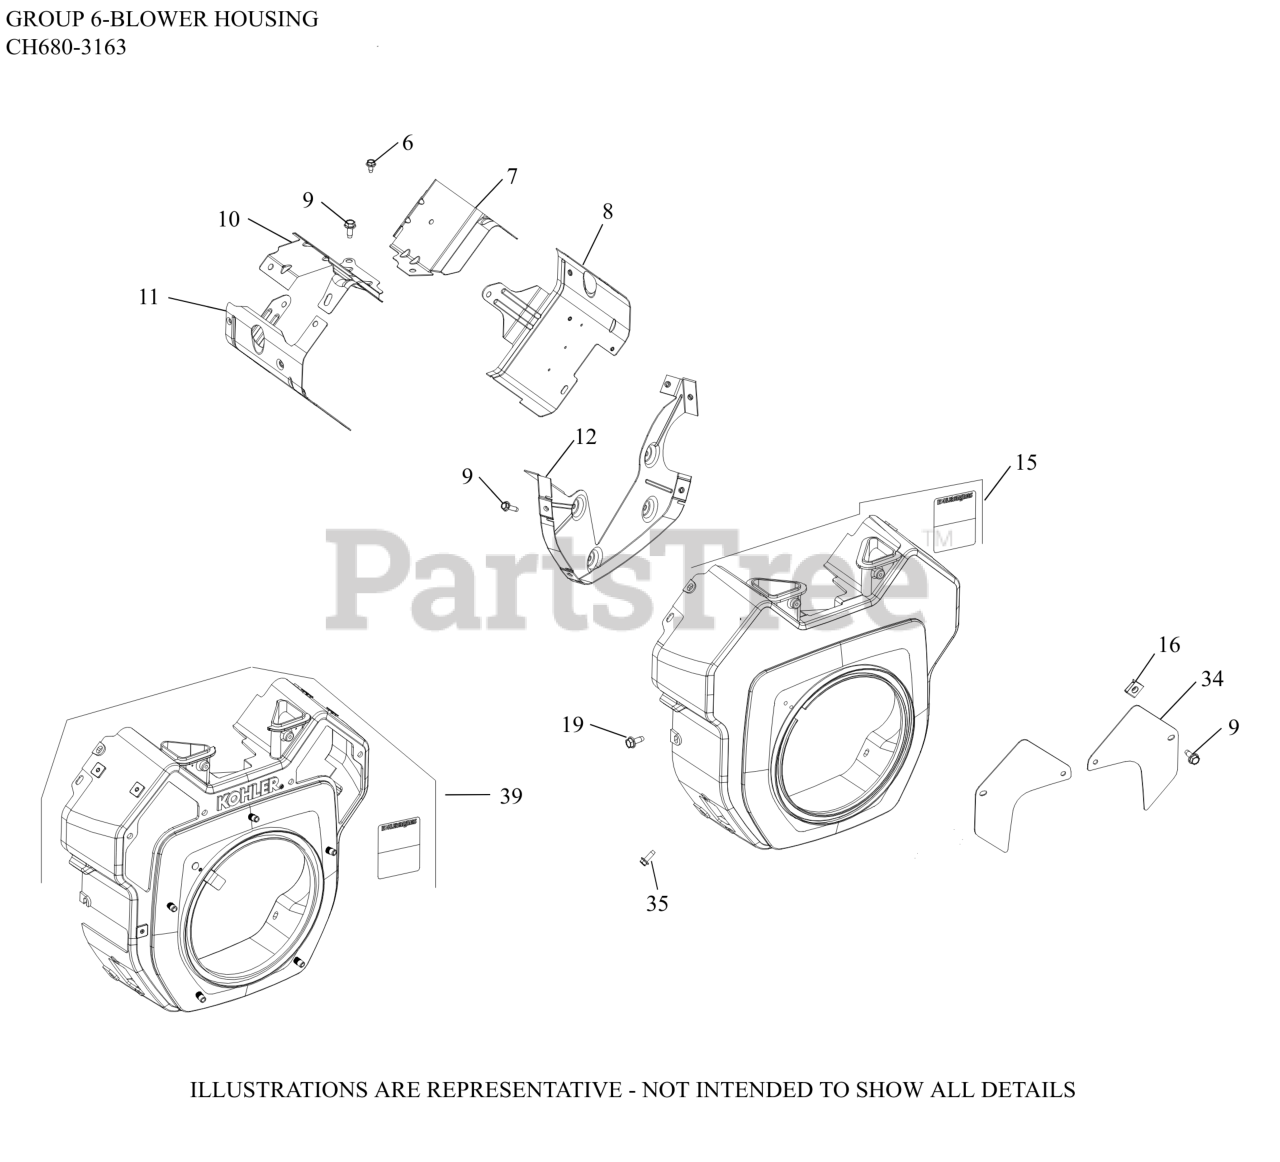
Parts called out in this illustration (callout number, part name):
6	SCREW, THREAD FORMING
7	BAFFLE, VALLEY #1 CYLINDER
8	KIT, CYL BAFFEL #1 SIDE
9	SCREW, THREAD FORMING
10	BAFFLE, VALLEY #2 CYLINDER
11	BAFFLE, LEFT BARREL
12	KIT, BACKING PLATE
15	HOUSING, BLOWER
16	CLIP, BAFFLE MOUNTING
19	SCREW, THREAD FORMING
34	KIT, ACCESS PANEL
35	SCREW, THREAD FORMING
39	KIT, BLOWER HOUSING
